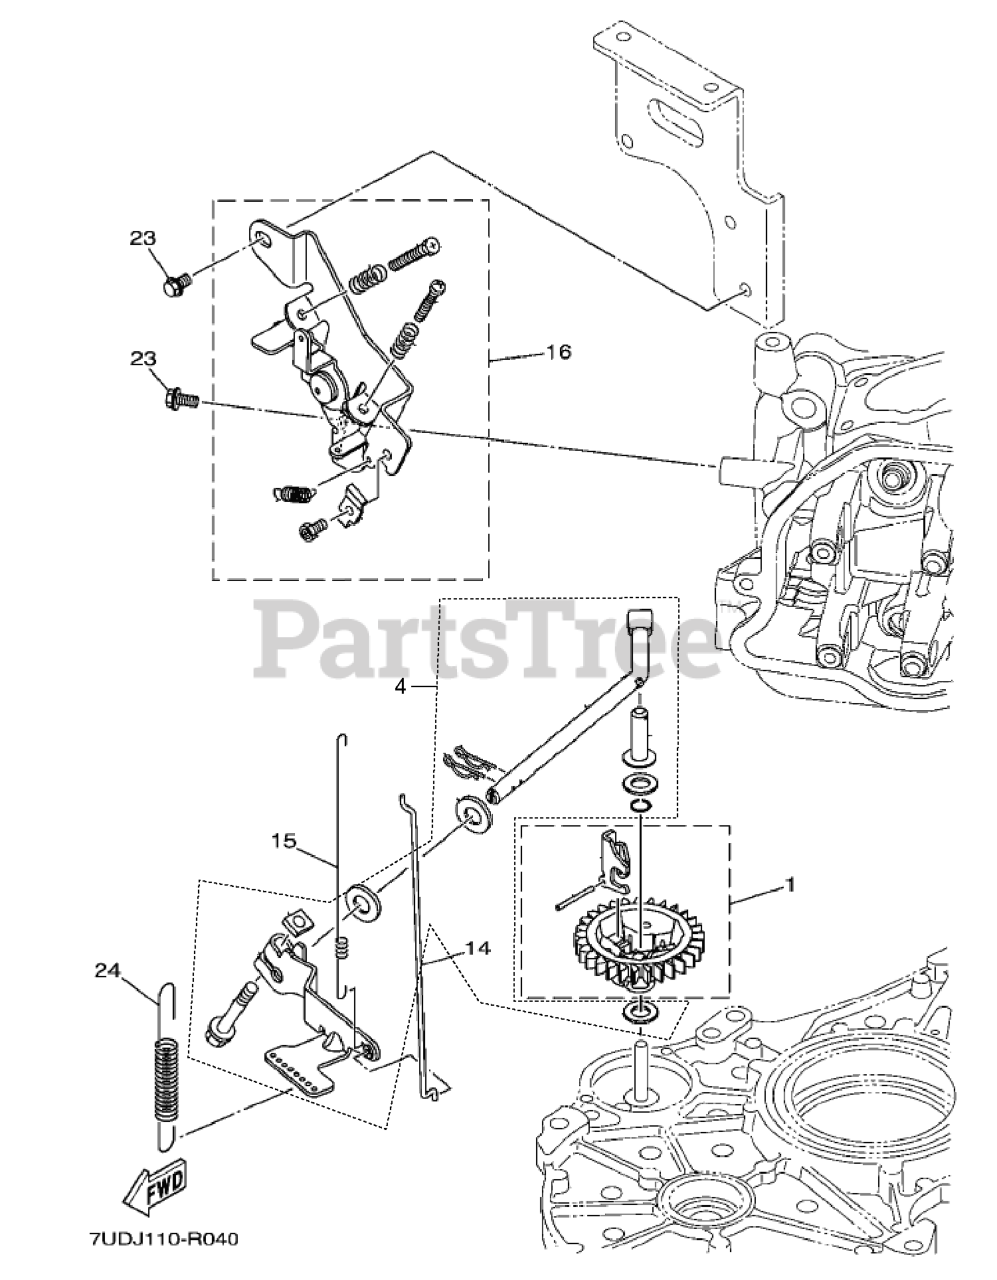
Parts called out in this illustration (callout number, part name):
1	GOVERNOR KIT
4	SHAFT ASSY FLYWEIGHT YAMAHA PN
14	ROD LINK YAMAHA PN: 7UD-E1928-
15	SPRING TENSION YAMAHA PN: 9050
16	THROTTLE LEVER COMP YAMAHA PN:
23	BOLT YAMAHA PN: 95802-06012
24	SPRING GOVERNOR YAMAHA PN: 7UD
